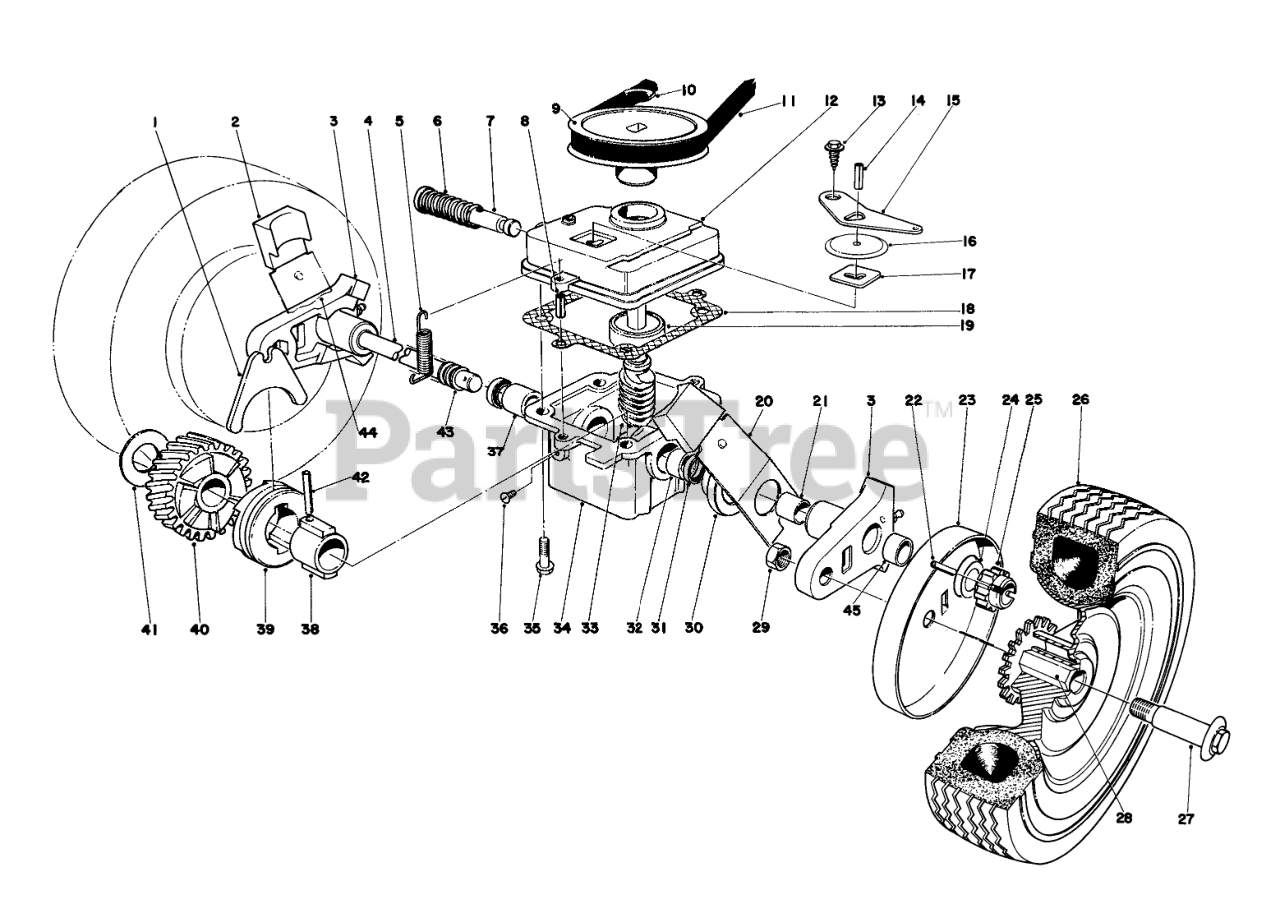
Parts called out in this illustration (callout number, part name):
1	SHIFTER FORK
2	KNOB-ARM
3	Pivot Arm (Incl. Ref. #21 & 45)
4	DRIVE SHAFT (SERVCE)
5	TENSION SPRING
6	SPRING
7	Shift Rod
8	3/16 X 1/2 ROLL PIN
9	PULLEY
10	PUSH-ON 93-3236
11	V BELT
12	Cover Gear Case
13	Bolt
14	PIN-ROLL
15	SHIFTER ARM
16	TRANS DUST COVER
17	LATCH PLATE
18	GASKET
19	Bearing
20	SPRING ARM ASM SP LH
21	BUSHING
22	Pin
23	WHEEL COVER
24	WASHER-THRUST
25	Pinion
26	Wheel & Tire Assembly (Incl. Ref. #28)
28	WHEEL BUSHING
29	Nut
30	End Cap
31	Seal
32	Bushing
33	Worm Shaft & Gear. (Incl. Ref. #40)
34	Gear Case (Incl. Ref. #31, 32 & 37)
35	Screw
36	NYLON SCREW
37	Bushing
38	SLEEVE
39	CLUTCH JAW
40	Helical Gear
41	THRUST WASHER
42	Pin
43	COVER-SHAFT, DRIVE
44	SPRING ARM ASM SP RH
45	BUSHING
